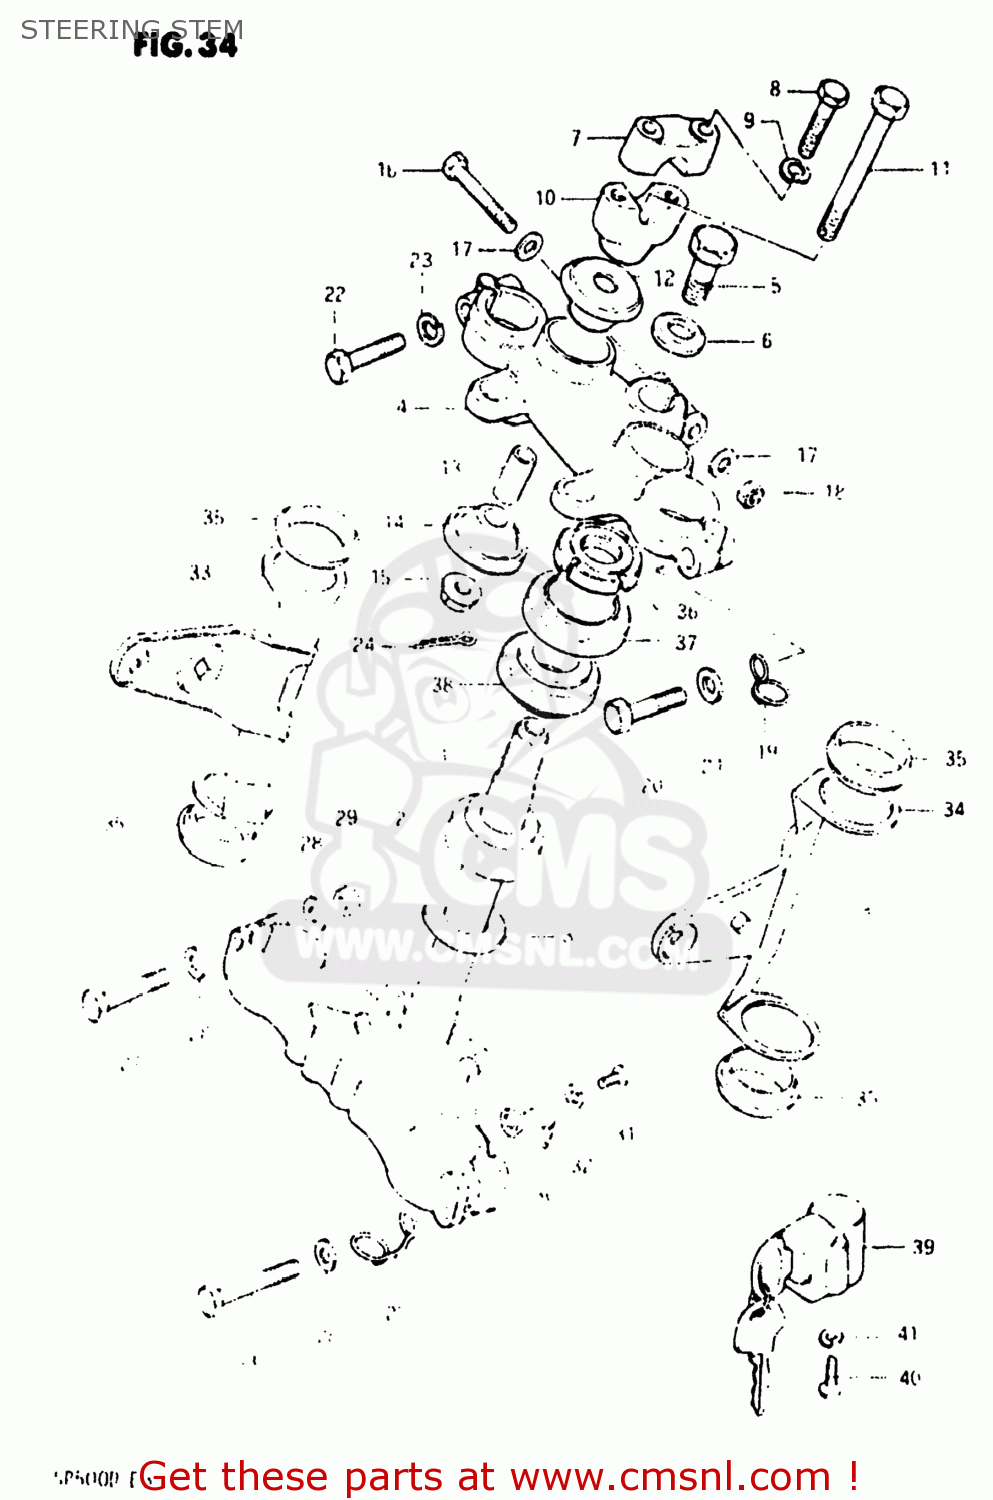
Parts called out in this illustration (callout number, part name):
1	STEM,STEERING
2	BEARING
3	WASHER,THRUST
4	HEAD,STEERING STEM
5	BOLT,STEERING STEM HEAD
6	WASHER
7	HOLDER,HANDLEBAR
8	BOLT
9	LOCK WASHER
10	HOLDER,HANDLEBAR
11	BOLT,HANDLE HOLDER
12	CUSHION,HANDLE,UPPER
13	SPACER(10.2X14X46)
14	CUSHION,HANDLE,LOWER
15	NUT
16	BOLT 8X55
17	WASHER
18	NUT
19	CLAMP,METER CABLE
20	BOLT 10X40
21	WASHER
22	BOLT,STEERING STEM HEAD
23	LOCK WASHER
24	PIN 20X20
25	GUIDE,CABLE
26	BOLT
27	BOLT 8X55
28	WASHER
29	NUT
30	CLIP,BRAKE CABLE
31	SCREW
32	LOCK WASHER
33	BRACKET,HEADLAMP,RIGHT
34	BRACKET,HEADLAMP,LEFT
35	CUSHION,HEADLAMP BRACKET
36	NUT,STEERING STEM(25X44X10)
37	DUST SEAL,STEERING,UPPER
38	TAPER,ROLLER BEARING
39	LOCK ASSY,STEERING
40	SCREW
41	LOCK WASHER
